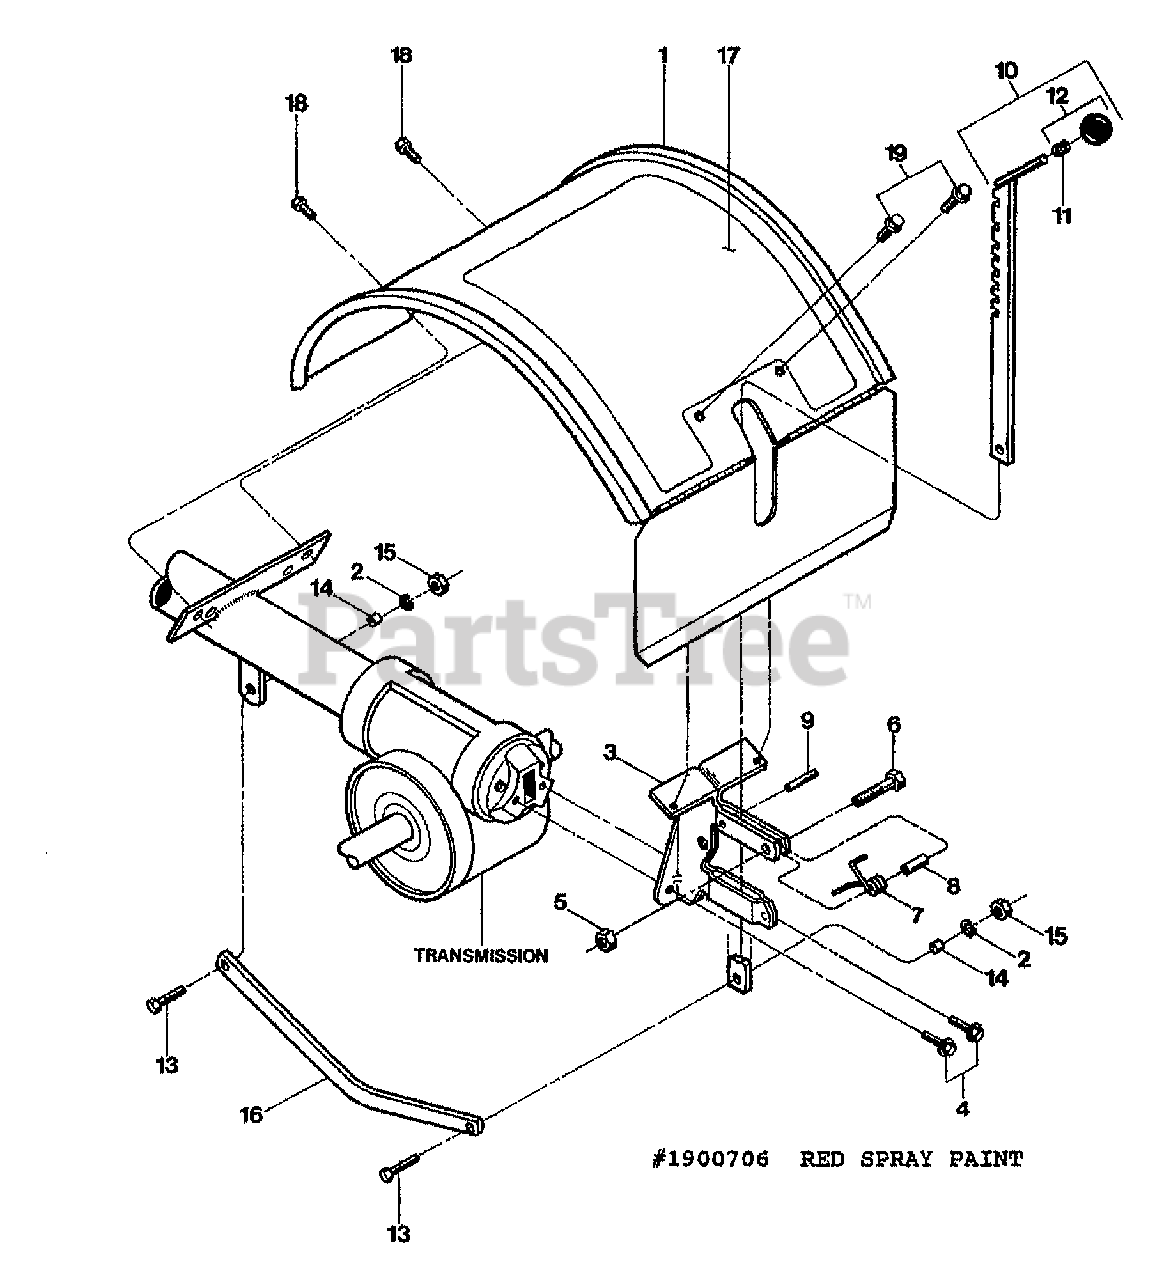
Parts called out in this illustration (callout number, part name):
1	HOOD W/DECALS PONY OPC (INCL. 17)
2	HOOD W/DECALS PONY (INCL 17) (15008,15009, 0400101 & HIGHER)
2	WASHER-LK .375 @ DEPL
3	BRKT W/ROLL PIN (9308)
4	SCR-HFLK 5/16-18X.62 G5ZP
5	NUT-LK 1/4-20
6	SCR-HH 1/4-20X1.0
7	SPRING-TORSION
8	SPACER-.250X.343X.375
9	PIN-ROLL .25 X 1
10	DEPTH REGULATOR W/KNOB (INCL. 11 & 12)
11	RING-TOLERANCE .5325 ID
12	KNOB-CONTROL (INCL. 11)
13	SCR-HH 3/8-16X1.25
14	BUSHING-.5X.375X.3
15	NUT-HEX 3/8-16 ZP
16	DRAG BAR-BENT
17	DECAL-HOOD OPER INST
17	DECAL-HOOD INST PONY (15008 & 15009 0400101 & HIGHER)
18	SCR-HWH 5/16-18 X .5 STH
19	SCR-HWH 1/4-20 X .5 STH (ATTACHES HOOD TO DEPTH REGULATOR BRACKET)
